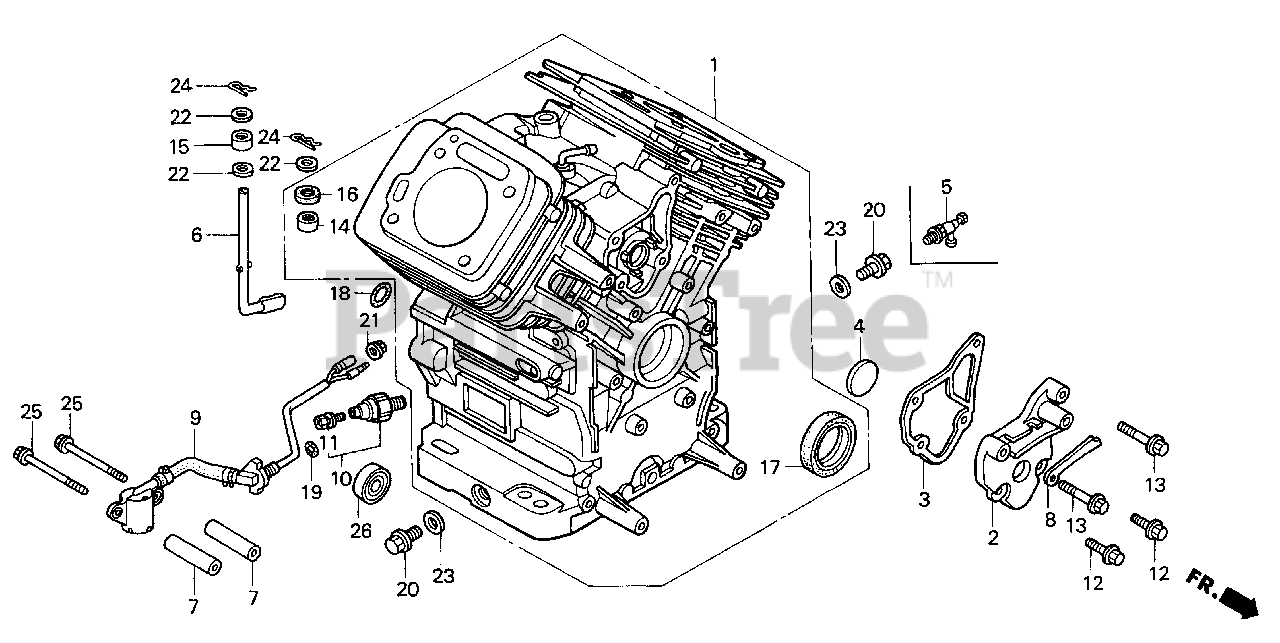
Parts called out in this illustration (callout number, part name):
1	CYLINDER ASSY. (OIL ALERT)
1	CYLINDER ASSY.
2	COVER, BREATHER
3	GASKET, BREATHER COVER
4	VALVE, BREATHER
5	VALVE, DRAIN (14X1.5)
6	SHAFT, GOVERNOR ARM
7	COLLAR, FILTER SETTING
8	CLAMP, WIRE
9	SWITCH ASSY., OIL LEVEL
12	BOLT, FLANGE (6X16)
13	BOLT, FLANGE (6X32)
14	BEARING, NEEDLE (8X12.7X11.1)
15	BEARING, NEEDLE (8X12X10)
16	OIL SEAL (8X14X5)
17	OIL SEAL (38X58X9)
18	O-RING (13X3.0)
19	O-RING (13.5X1.5) (ARAI)
20	BOLT, DRAIN PLUG (14MM)
21	NUT, FLANGE (10MM)
22	WASHER, PLAIN (8MM)
23	WASHER, DRAIN PLUG (14MM)
24	PIN, LOCK (8MM)
25	BOLT, FLANGE (6X75)
26	BEARING, RADIAL BALL (6003)
